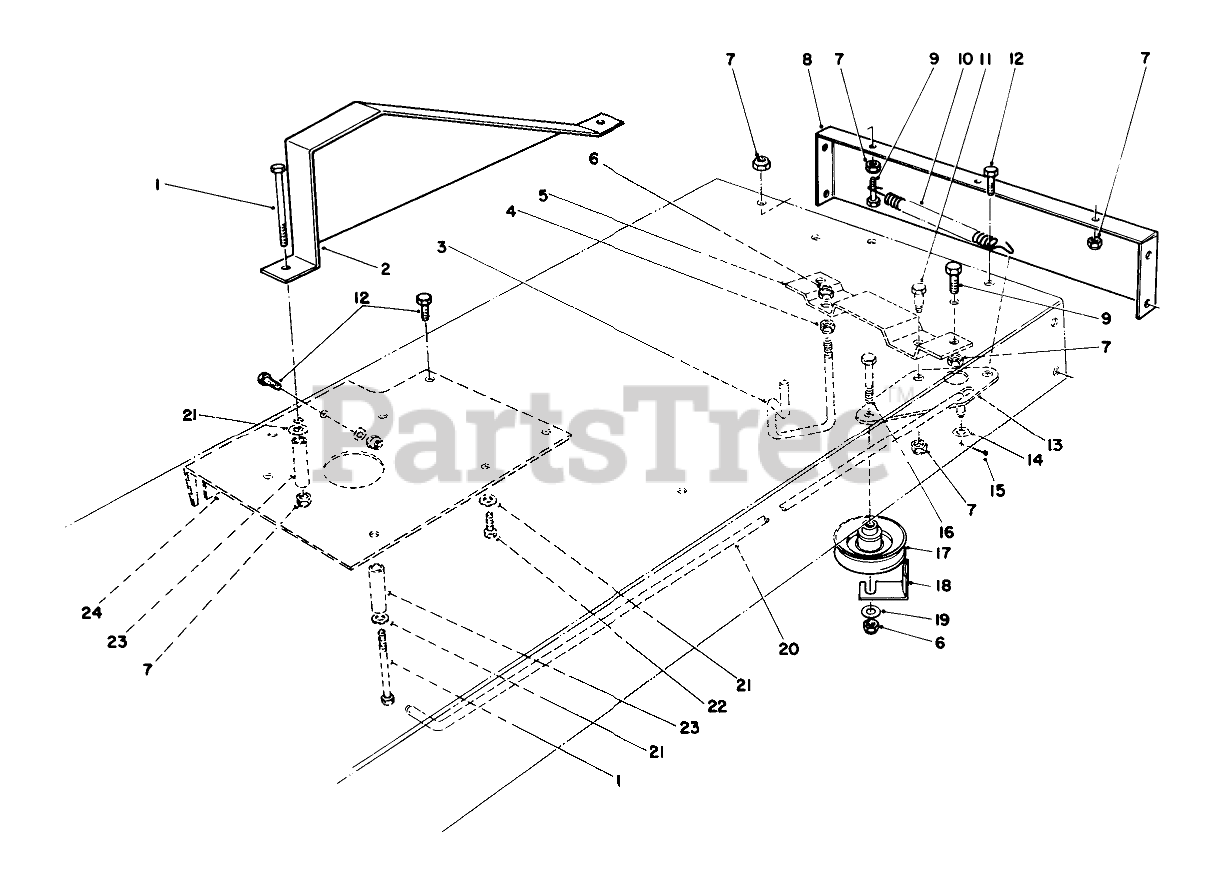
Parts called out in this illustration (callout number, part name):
1	SCREW-HH
2	CHAIN GUARD R
3	BELT GUIDE
4	NUT-LOCK, SIDE
5	TRACT SUPP BRKT B
6	NUT-LOCK, CONE
7	NUT-LOCK, NI
8	REAR FRAME R
9	SCREW-HH
10	TRACTION SPRING
11	BOLT-SHOULDER
12	SCREW-HH
13	TRACTION PIVOT BRKT
14	WASHER-FLAT
15	PIN-COTTER
16	SCREW-HH
17	PULLEY-IDLER
18	RETAINER-BELT
19	WASHER-FLAT
20	TRACTION ROD
21	WASHER-PLAIN
22	Screw-HH
23	OUTER TUBE SPACER
24	REINF PLATE R
